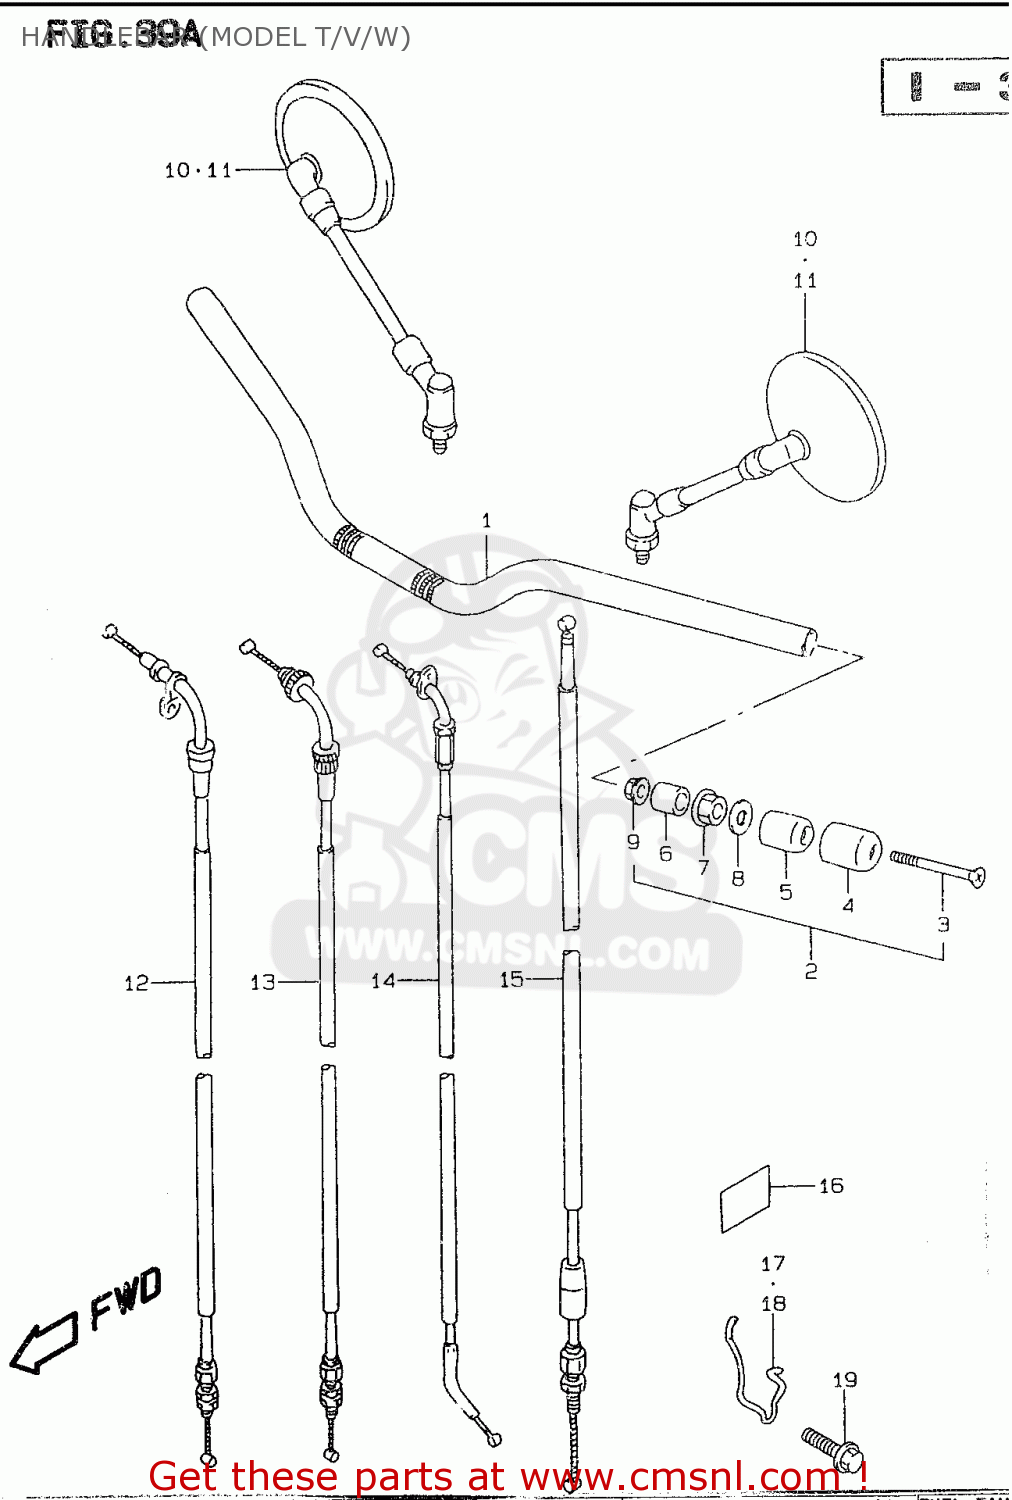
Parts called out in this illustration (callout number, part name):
1	HANDLEBAR
2	BALANCER SET,HANDLEBAR
3	SCREW
4	CAP,BALANCER
5	BALANCER,HANDLE
6	SPACER,BALANCER
7	NUT
8	EXPANDER,HANDLE BALANCER
9	NUT
10	MIRROR ASSY,RH
11	MIRROR ASSY,RH
12	CABLE ASSY,THROTTLE NO.1
13	CABLE ASSY,THROTTLE NO.2
14	CABLE COMP,STARTER
15	CABLE ASSY,CLUTCH
16	PROTECTOR,FRAME COVER FR
17	GUIDE,CABLE NO.1
18	GUIDE,CABLE NO.2
19	BOLT
